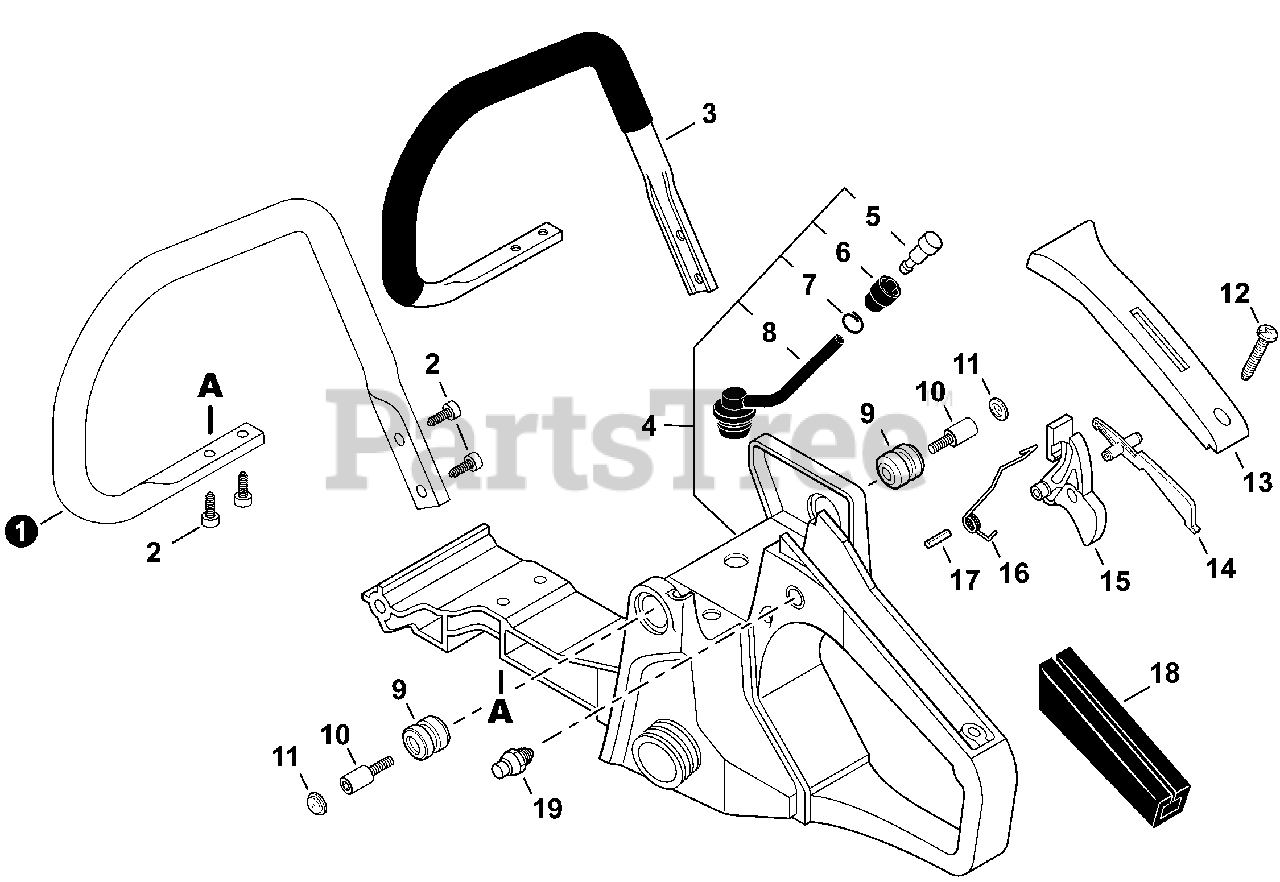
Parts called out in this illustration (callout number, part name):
1	HANDLE, FRONT
2	BOLT 5×20
3	HANDLE, FRONT - ALUMINUM
4	HANDLE ASSY, REAR
5	VENT ASSY
6	HOLDER, VENT
7	CLIP 6.5 MM
8	PIPE, VENT 3×6×65
9	CUSHION 4
10	BOLT 4×10×13.5
11	CAP, CUSHION
12	SCREW 4×14
13	COVER, HANDLE
14	LOCKOUT, THROTTLE
15	TRIGGER, THROTTLE
16	SPRING, TORSION
17	PIN, SPRING 4×30
18	GRIP, HANDLE
19	LOCK, THROTTLE TRIGGER
